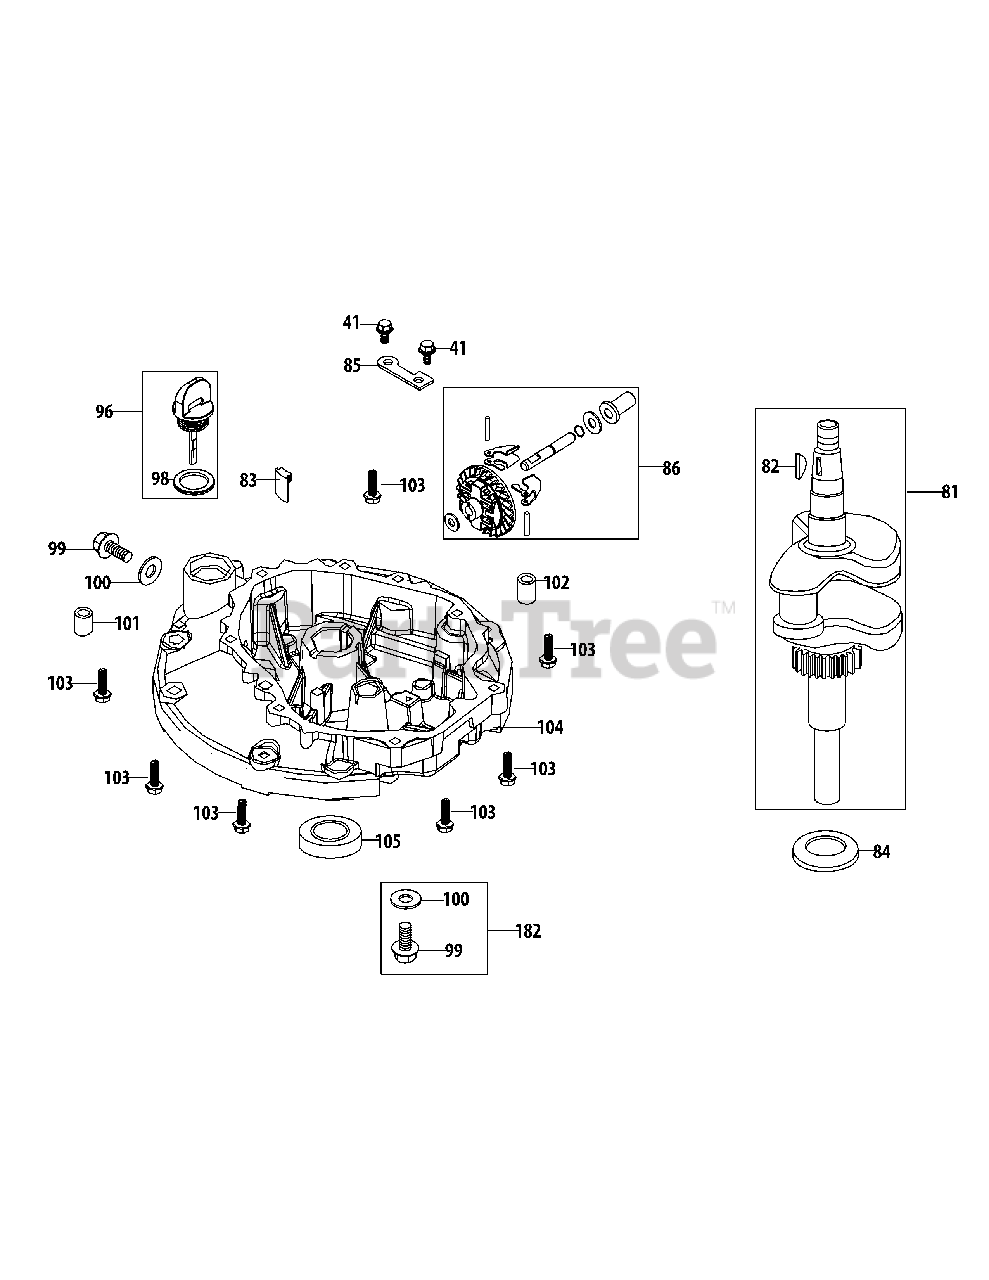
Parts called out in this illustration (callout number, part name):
41	Bolt M6X14 Multi-Purpose
81	Crankshaft Assembly
82	Woodruff Key
83	Oil Return Seal
84	Crankshaft Thrust Washer
85	Governor Gear Mounting Plate
86	Governor Gear/Shaft Assembly
96	Dipstick Assembly
98	Dipstick O-Ring
99	Oil Drain Plug
100	Oil Drain Plug Washer
101	Crankcase Cover Dowel Pin 9×14
102	Crankcase Cover Dowel Pin 7×14
103	Bolt M6X28 P65 Crankcase
104	Crankcase Cover
105	Lower Crankshaft Seal
182	Oil Drain Plug & Washer Assy
